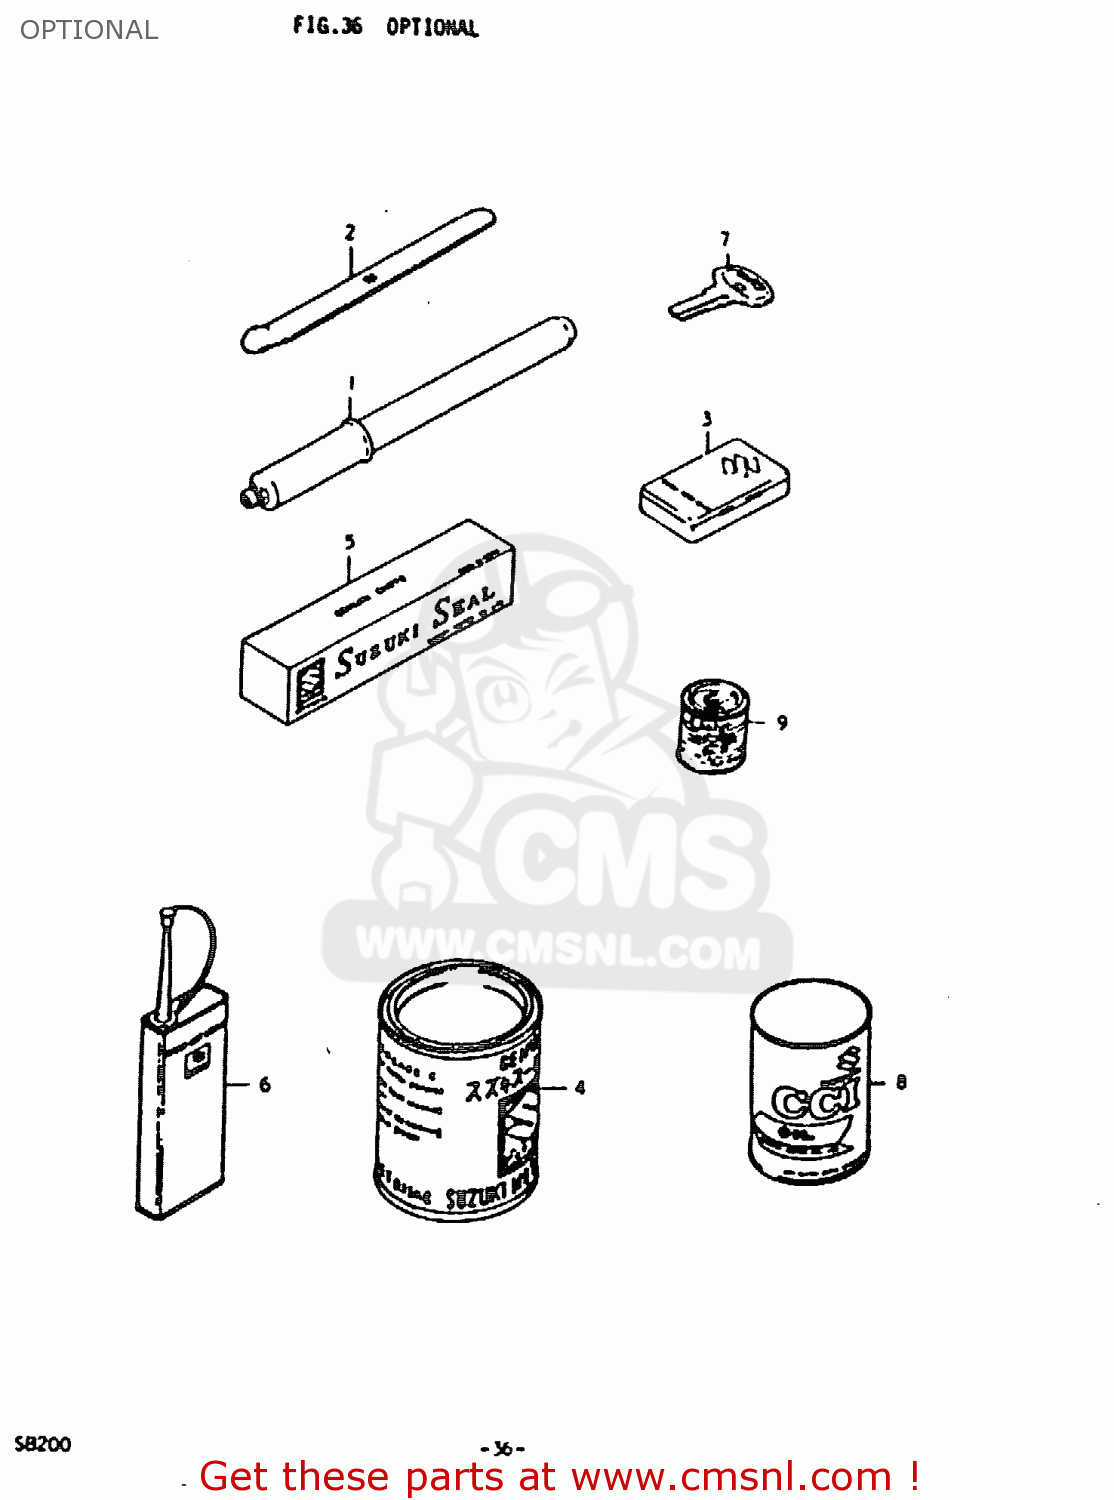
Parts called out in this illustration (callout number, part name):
1	INFLATOR, AIR
2	LEVER,TIRE
3	TUBE REPARING TOOL
4	GREASE(C)EP2 LITHIUM 150G
5	LIQUID GSKT 150G BLACK
6	THREAD LOCK NO.1401 CLEAR 200G
7	KEY,BLANK
8	CCI OIL
9	PAINT (MARBLE PURE RED)
